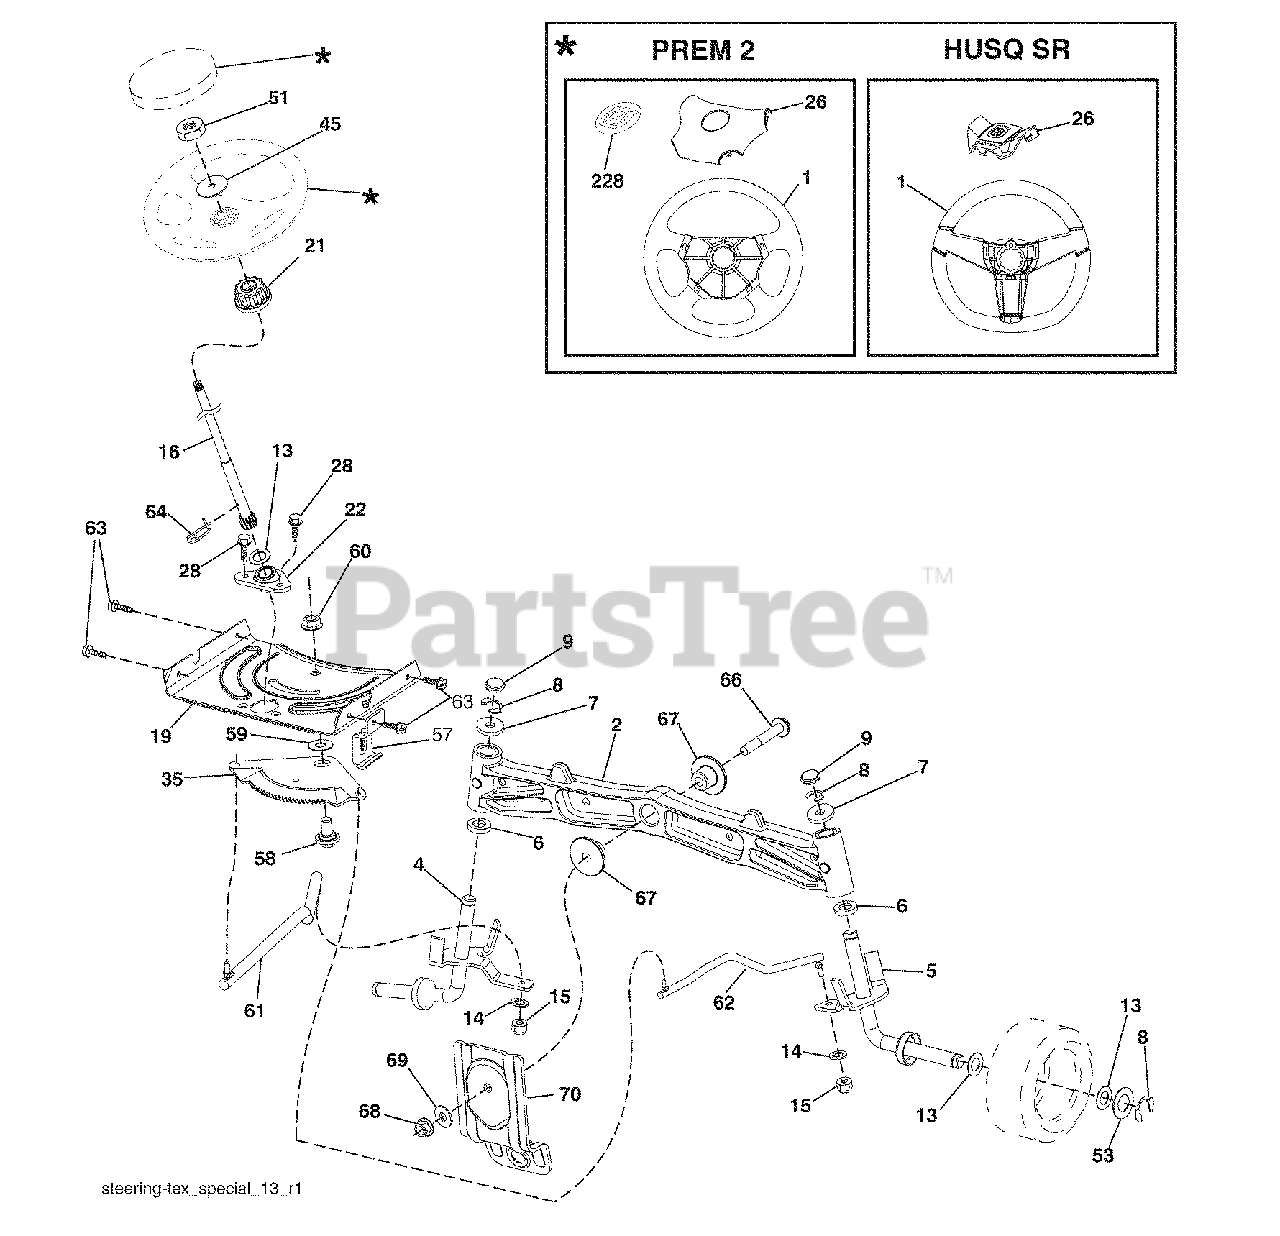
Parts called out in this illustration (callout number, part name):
1	Wheel, Steering
2	Axle Asm., Front
4	Spindle Asm., LH
5	Spindle Asm., RH
6	Bearing, Race Thrust Harden
7	Washer 25/32 x 1-5/8 x 16 Ga.
8	Ring, Clip #T5304-75
9	Cap, Spindle
13	Washer 25/32 x 1-1/4 x 16 Ga.
14	Washer, Lock Hvy Hlcl Spr 3/8
15	Nut, Crown Lock 3/8-24 unf
16	Shaft Steering
19	Plate Steering
21	Adapter, Wheel Steering
22	Bushing, Strg. Blk
26	Insert, Wheel Steering
28	Screw 3/8-16 x 3/4
35	Gear, Sector Plate
45	Washer 9/16 x 2-3/8 x 12 Ga.
51	Nut Hex Jam Toplock 1/2-20 unf
53	Washer Hardened .793 x 1.637 x .060
57	Bracket Upstop
58	Bolt Shoulder Sector Pivot CFM
59	Washer Thrust Sector Steering
60	Nut Flange Lock 5/8-11
61	Draglink, LH
62	Draglink, RH
63	Screw 5/16-18 x 3/4
64	Retainer Clip Spring Steering
66	Bolt Hex Fghd 7/16-14 x 3 Serr
67	Bushing PM Front Axle
68	Nut Lock Flange 7/16-14 Gr. 5
69	Washer 1.5 x .505 x .118
70	Bracket Deck Susp. Front
228	Decal Wheel Steering
